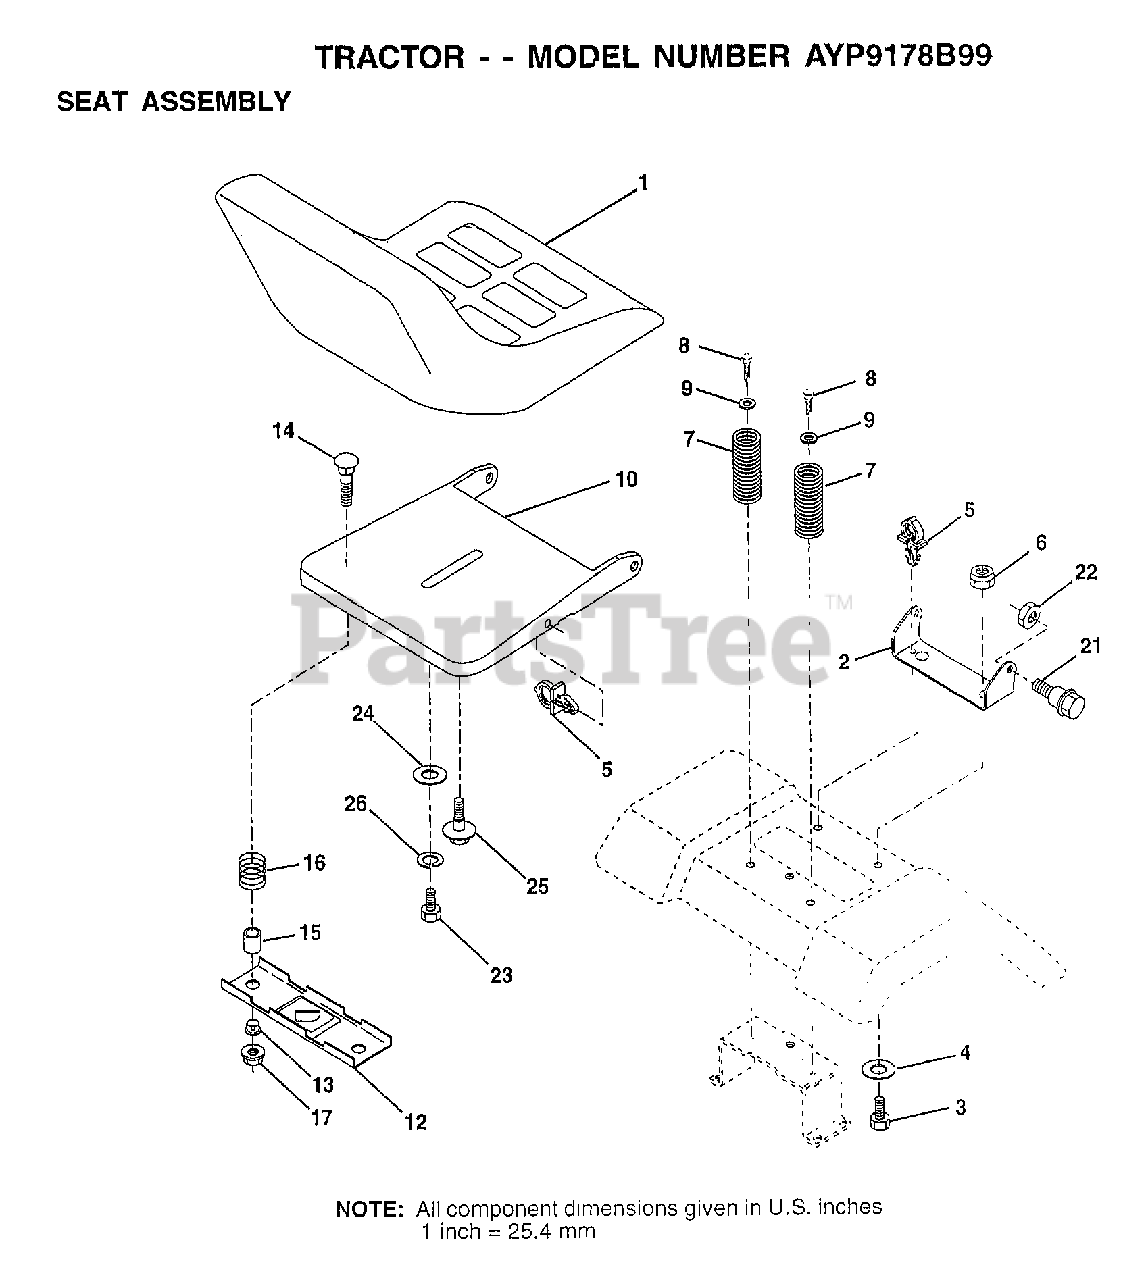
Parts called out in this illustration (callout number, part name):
1	SEAT.2400/1416.BK
2	BRACKET PVT SEAT
3	BOLT
4	WASHER PM
5	CLIP.PUSH-IN.HING
6	NUT
7	SPRING COMPRESSIO
8	SCREW GTV
9	WASHER
10	PAN-SEAT
12	BRKT SWITCH
13	BUSHING
14	BOLT-RD HD SQ NK
15	SPLIT SPACER
16	SPRING
21	"BOLT,SHOULDER"
22	NUT
23	BOLT
24	WASHER
25	"BOLT,SHOULDER"
26	LOCKWASHER
